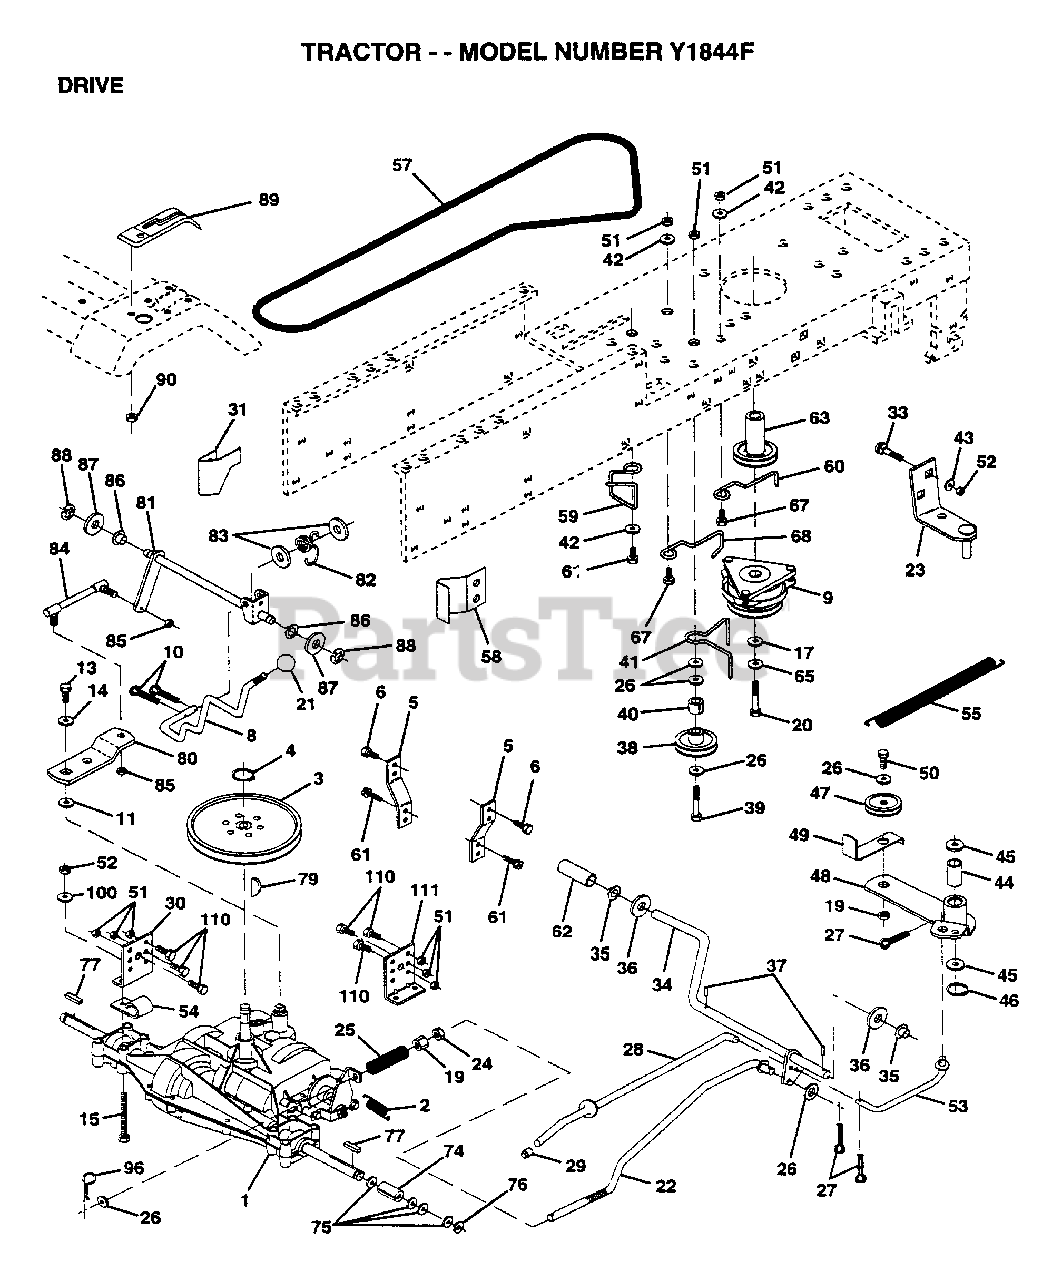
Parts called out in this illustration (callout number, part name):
1	TRANSAX. PRLES.
2	SPRING.BRAKE.RETU
3	PULLEY TRANSAXLE
4	RING
5	STRAP TORQUE
6	SCREW
10	PIN COTTER 1/8
11	WASH-SHFT PLT LT
13	BOLT.1/4-28.W/PAT
14	WASHER PM
15	BOLT HEX
17	WASHER
19	NUT
21	KNOB T (1/2-HOLE)
22	ROD.ASM.BK.44.MWR
23	BRACKET.ASM.MTG
24	NUT
25	"SPRING,ROD BRAKE"
26	WASHER
27	COTTER PIN
28	ROD.BRAKE.PARK.LT
29	PLUNGER CAP T
30	BRKT TRANS LH
31	KEEPER BELT LH
33	BOLT
35	NYLON BEARING
36	WASHER LT
38	PULLEY.IDLER.FLAT
39	BOLT
40	SPACER T
41	BELT KEEPER LT
42	WASHER
43	WASHER T
44	"LY, BEARING"
45	WASHER LT
46	KLIP RING
48	ARM IDLER
49	RETAIN BELT
52	NUT
53	"LINK, CLUTCH T"
54	CLIP T
55	"SPRING, RETURN LT"
57	BELT.GRDRV.94.75
58	"KEEPER,BELT RH"
59	KEEPER BELT CNTSP
60	KEEPER BELT ENGLH
61	SCREW
62	PEDAL COVER T
63	PULLEY ENGINE
65	LOCKWASHER
67	BOLT
68	"KEEPER,BLT ENG LT"
74	SPACER HYT
75	WASHER
76	E RING HYT
77	SQ KEY STD
80	"ARM,SHIFT"
81	"SHAFT,SHIFTER"
83	WASHER
84	"ROD,TIE "
85	NUT 1/4-28
86	BUSHING
87	WASHER D
88	KLIP RING
89	CONSOLE SHIFTER
90	NUT
96	RETAINER M
100	WASHER M
111	BRKT TRANS RH
